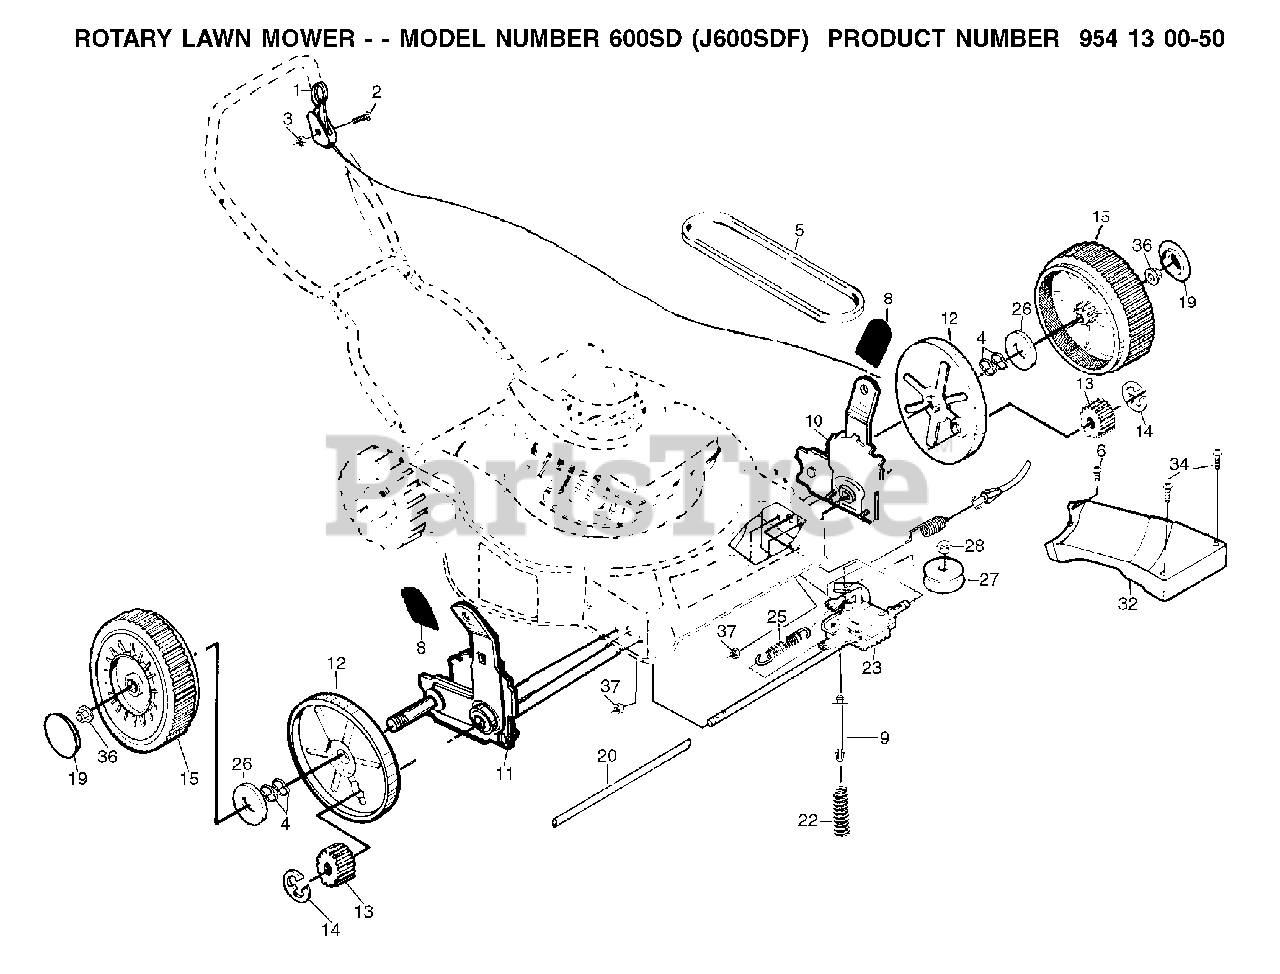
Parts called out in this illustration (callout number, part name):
1	CONTROL
4	WAVE WASHER
5	BELT THERM .32
6	TAPPING SCREW
8	SELECTOR KNOB
9	SPRING RETAINER
12	DUST COVER, WHEEL
13	PINION GEAR
14	E-RING 7/16 RE
15	WHEEL.8X2.RADIAL.GRAY
20	DRV SHAFT TUBE PM
22	SPRING.EXTENSION
23	GEAR CASE ASMBLY
26	WASHER FLUT
27	PULLEY
28	FLANGED LOCKNUT 3/8-16 ZINC
36	HEX FLANGE LOCKNT
37	NUT
